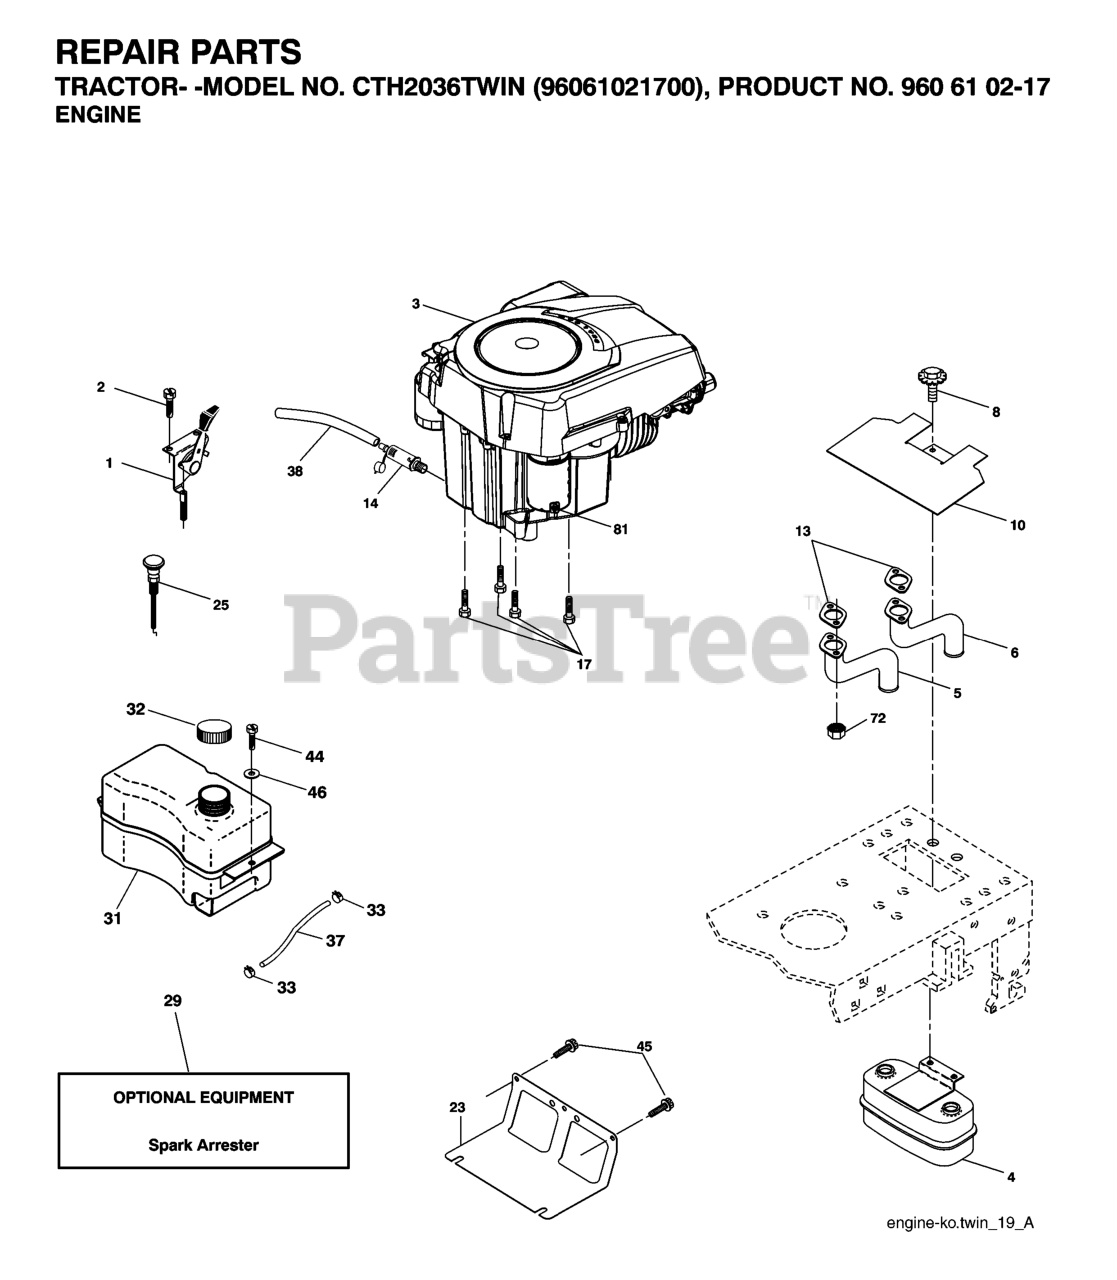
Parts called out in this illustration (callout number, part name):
1	THROTTLE CONTROL
2	SCREW
4	MUFFLER.TWIN.CYL.LOW.TONE
5	RP.PIPE-EXHAUST LH
6	RP.PIPE-EXHAUST RH
8	BOLT.5/16-18UNCX3/4 W/SEMS.BLK
10	RP SHIELD HEAT MUFFLER
14	TUBE, DRAIN OIL ASM.
17	SCREW 3/8-16X1
23	SHIELD.BROWNING.DBR.GUARD
25	CONTROL, CHOKE
29	KIT.SPARK ARRESTOR 794945 B&S
31	TANK.ASM.FUEL.FR.2.5GA.
32	FUEL CAP
33	HOSE CLAMP
37	LINE.FUEL.20
38	PLUG DRAIN OIL EASY
44	SCREW HEXWSHR 1/4-20X3/4
45	SCREW, 3/8-16X3/4
72	SCREW.SOCKET HD.5/16-1
81	NUT
